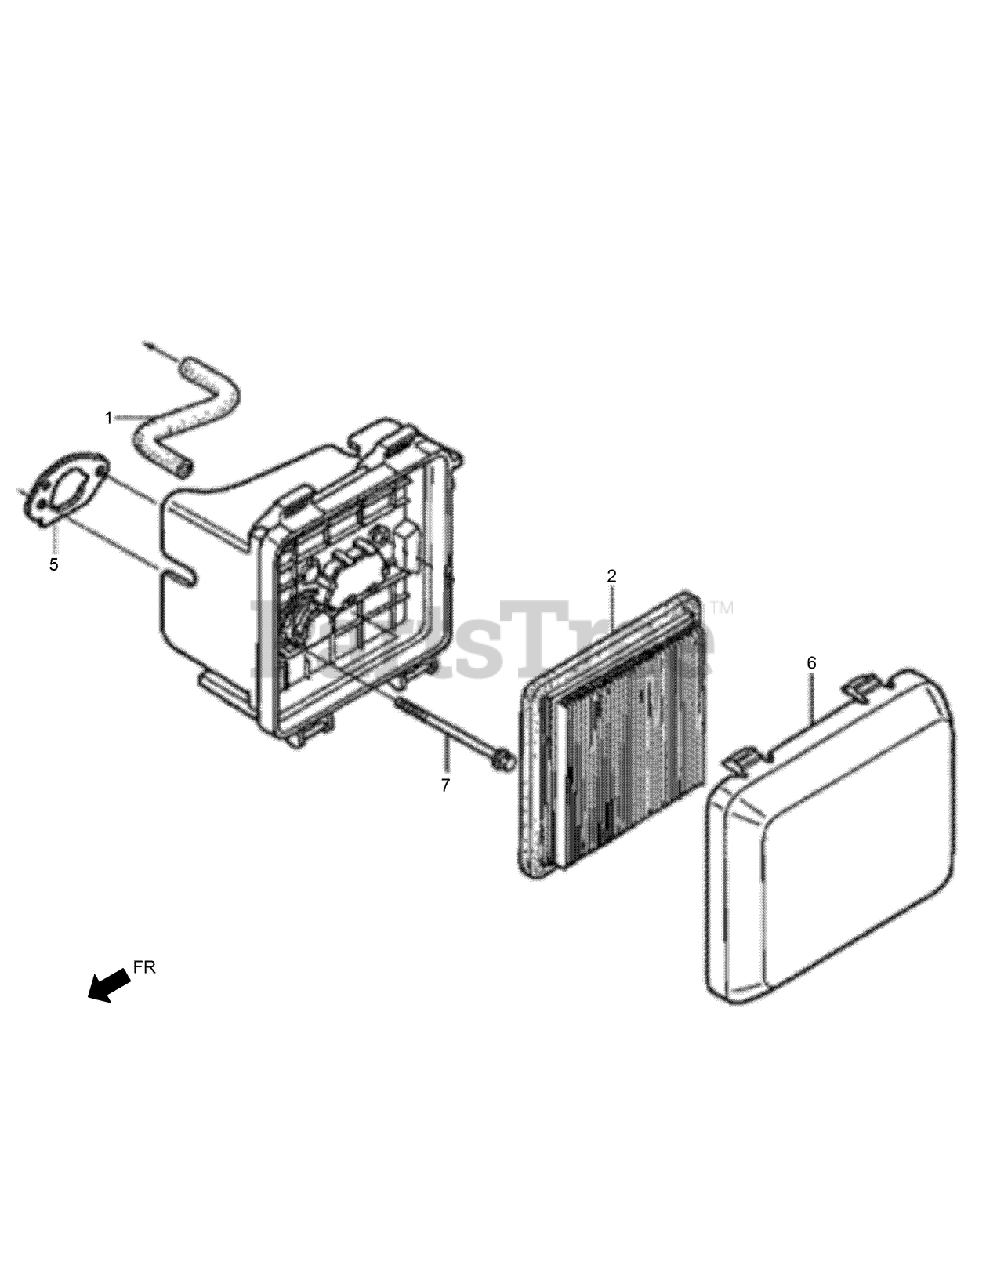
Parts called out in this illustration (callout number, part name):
1	TUBE-BREATHER
5	PACKING-AIR CLEANER
6	COVER-AIR CLEANER
7	BOLT-FLANGE-6X85
